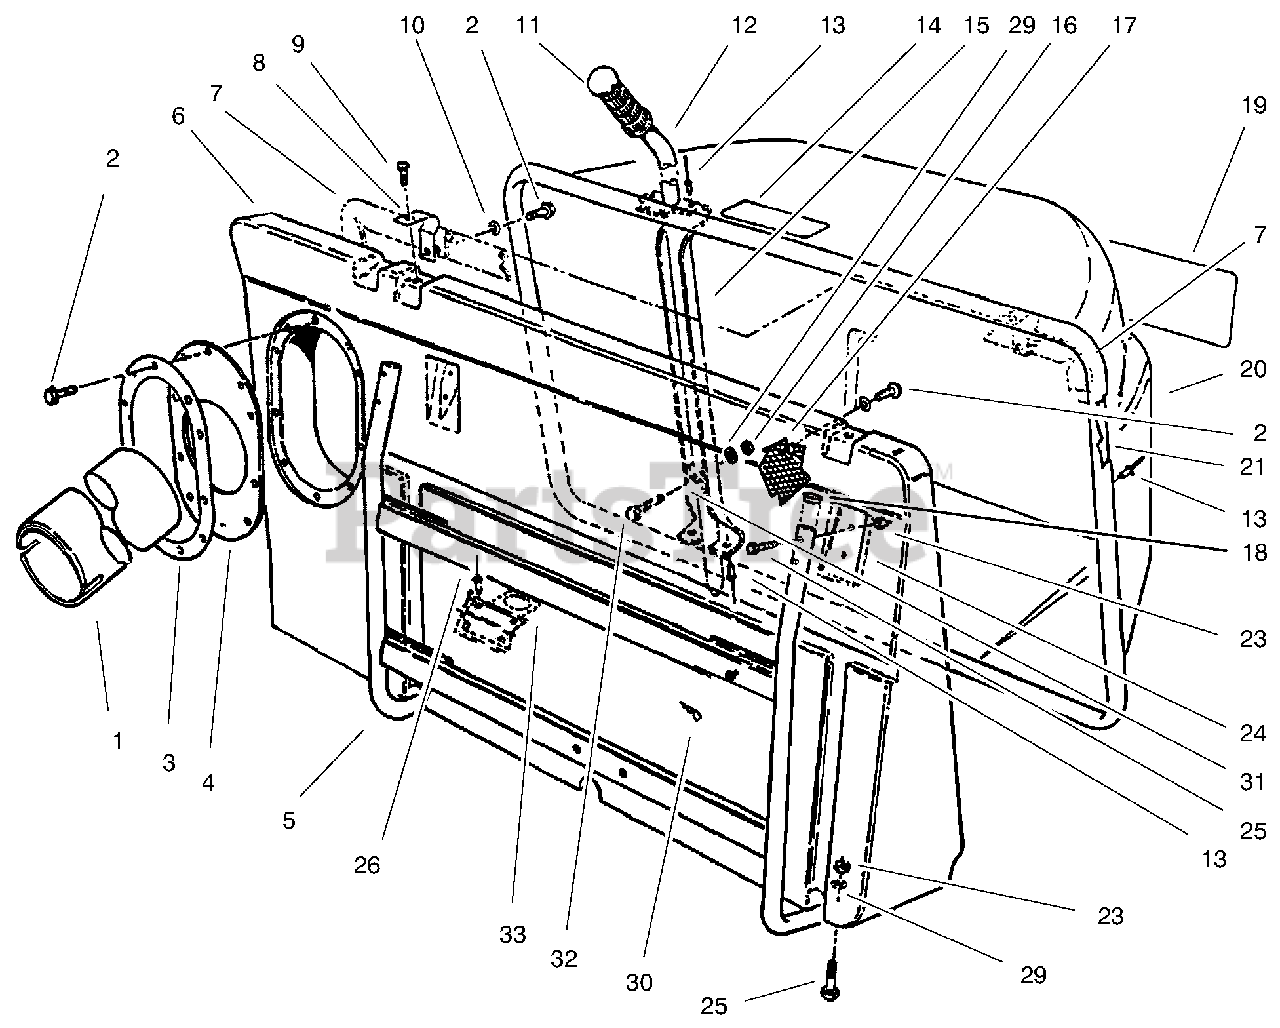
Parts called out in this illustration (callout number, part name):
1	DUCT - BAGGER
2	SCREW-FORMING, THREAD
3	RET RING
4	RUBBER RETAINER RING
5	Frame
6	BAG FRONT
7	BAG SEAL
8	Bracket-Hinge
9	SCREW-HH
10	WASHER-FLAT
11	HANDLE GRIP
12	DUMP HANDLE
13	RIVET-POP
14	DECAL - WARNING
15	Channel-Dump Handle
16	NUT-LOCK, NI
17	Screen Bag
19	EASY EMPTY BAG DECAL
20	GRASS BASKET
21	Frame-Grass Basket
23	NUT-LOCK, NI
24	Plate-Backup
25	SCREW-HH
26	RIVET-POP
29	WASHER-FLAT
31	DUMP HANDLE GUIDE
32	SCREW-HH
33	Latch
